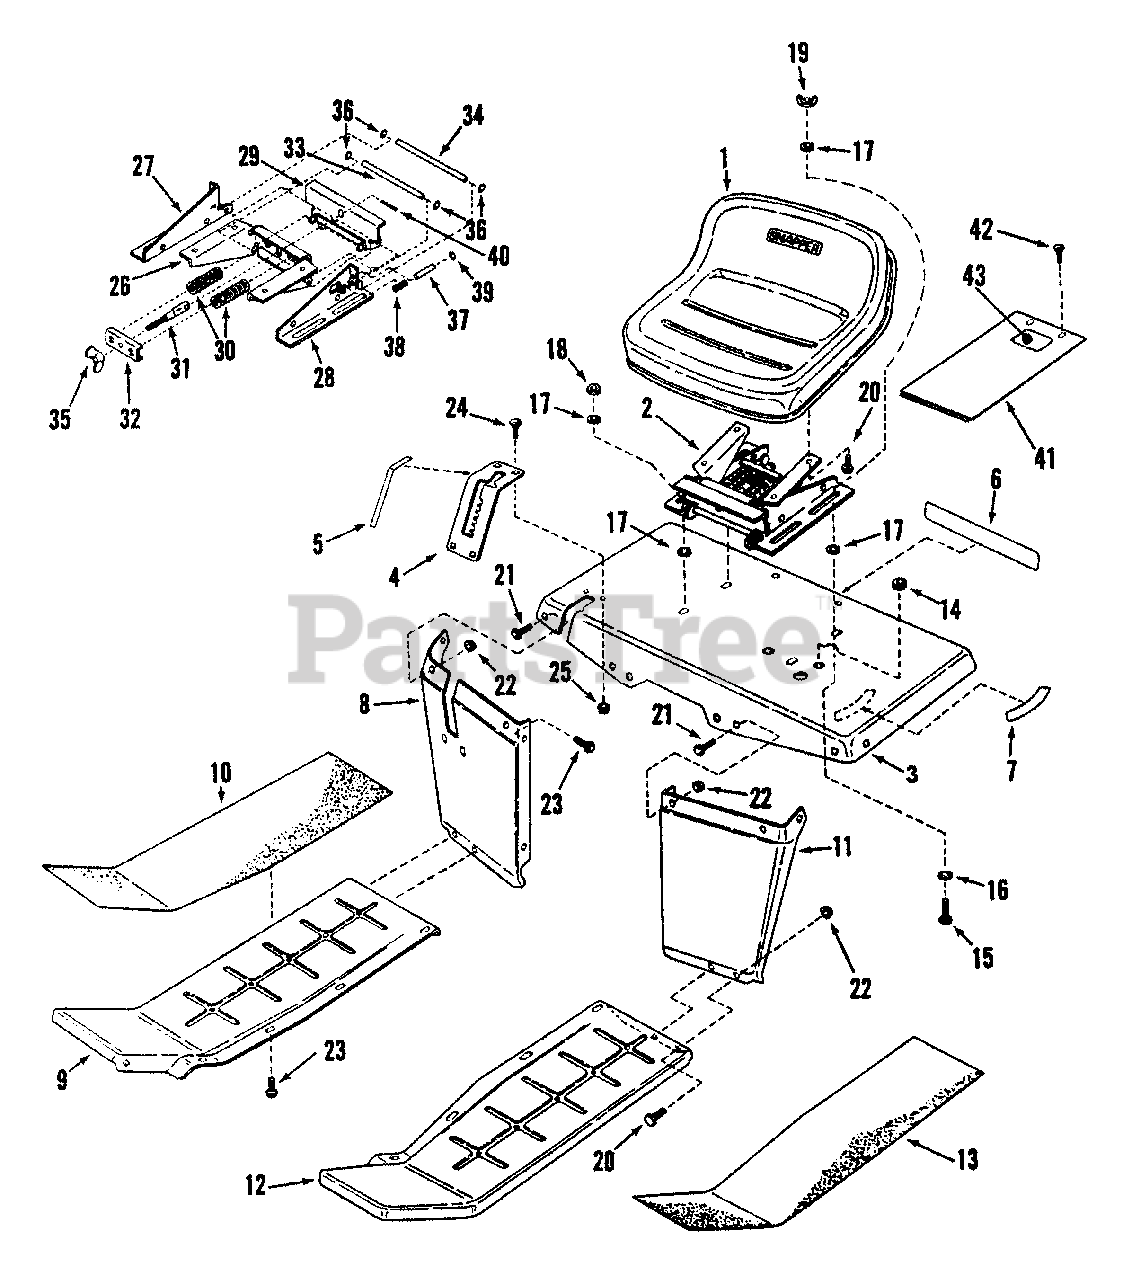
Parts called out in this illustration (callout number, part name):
1	SEAT, Operator's
2	ASSEMBLY, Seat Suspension (No Longer Available)
3	FENDER, Rear
4	DETENT, Shift
5	DECAL, Speed Shift (No longer available)
6	DECAL, SNAPPER
7	DECAL, Hl-LOW RANGE (Shift)
8	EXTENSION, Right Side Fender (No longer available)
9	PANEL, Right Side Step
10	TREAD, Right Side (No longer available)
11	EXTENSION, Left Side Fender (No longer available)
12	PANEL, Left Side Step
13	TREAD, Left Side (Non-Skid)
14	GROMMET, 5/16 I.D. for .75 Hole (NLA)
15	BOLT, 5/16-18 x 1" Square Neck Carriage
16	RETAINER, 5/16 Bolt
17	WASHER, 5/16" x 1-1/4" x 3/32" Flat
18	NUT, 5/16-18 Hex Center Lock, Grade B or 5
19	WING-NUT, 5/16-18
20	BOLT, 5/16-18 x 1/2 Hex Flange Lock, Grade 5
21	BOLT, 5/16-18 x 1/2" Short Neck Carriage, Grade 5
22	NUT, 5/16-18 Hex Flange Lock, Grade 5
23	SCREW, 5/16-18 x 5/8" Self-Tap
24	BOLT, 1/4-20 x 1/2" Short Neck Carriage, Grade 5
25	NUT, 1/4-20 Hex Flange Lock
26	WELDMENT, Seat Hinge
27	ANGLE, L.H. Mounting
28	ANGLE, R.H. Mounting
29	WELDMENT, Seat Hinge (NLA)
30	SPRING, Seat
31	ROD, Adjusting
32	RETAINER, Spring
33	PIN, Seat Tilt Hinge
34	PIN, Seat Tilt Hinge (3/8x12)(NLA)
35	WING-NUT, 1/2-13
36	PUSHNUT, 3/8
37	PLUNGER (5/16x2.42)
38	SPRING, Compression
39	PIN, 3/32 x 3/4" Cotter
40	GROOVED PIN, 3/16 x 1-3/4"
41	COVER, Access (NLA)
42	SCREW, 5/16-18 x 1/2" Hex Washer Self-Tap
43	DECAL, Seat Adjustment
